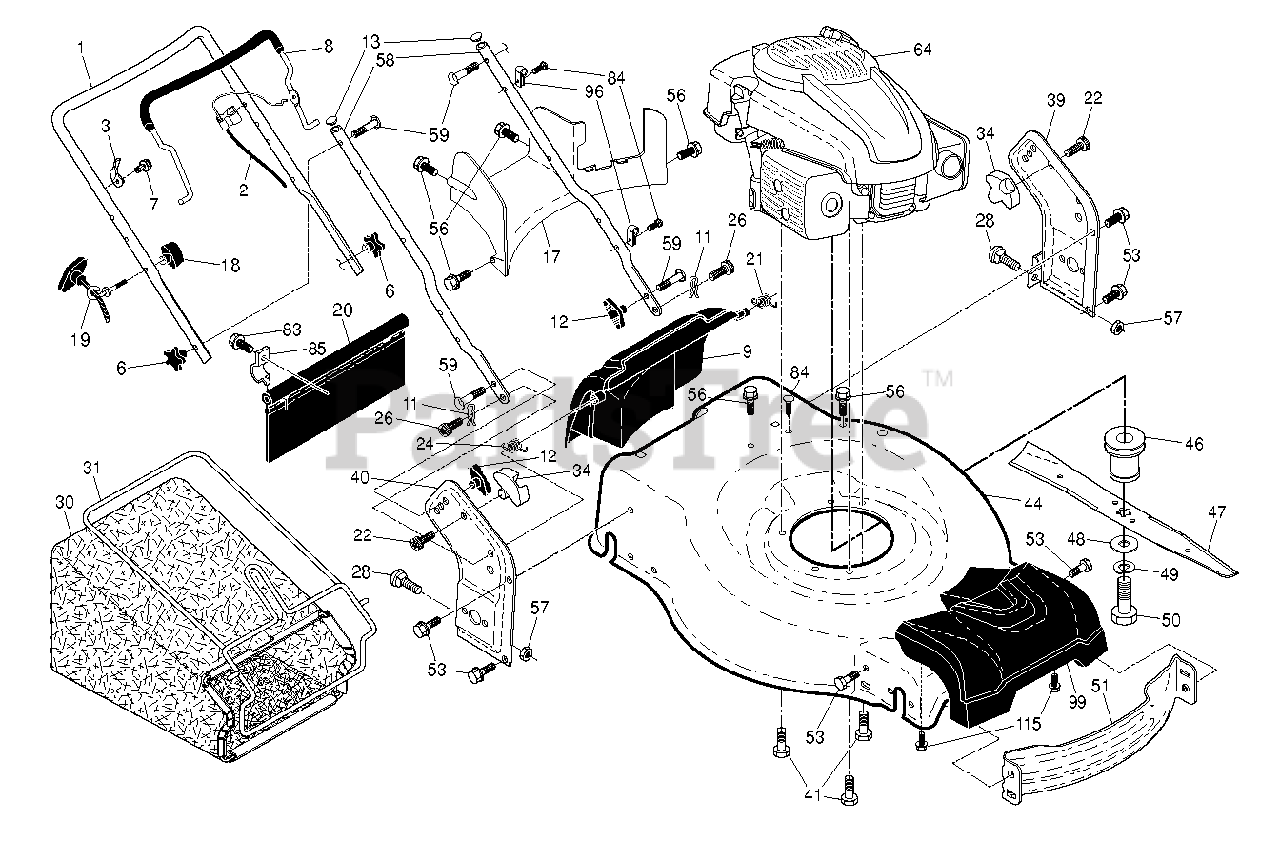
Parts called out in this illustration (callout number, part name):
1	HANDLE.UP.DSTR.FG/RGD.BLACK
2	Cable, MZR Rgd Plus Strt
3	BRACKET.UPSTOP.RT
6	KNOB.HANDLE.PLASTIC.STAR.BLACK
8	Bail, OM Strt.Mzr.Black.428
9	DOOR.REAR.22+GEN.RG.EBA.BLK
11	COTTER.HAIRPIN.DOOR/HANDLE.PIV
12	KNOB, DEFLECTOR
13	PLUG.PLASTIC.7/8".14-20.GAUGE
17	Rear Baffle, 22+ Rgd AWD Plastic
18	T-Knob, New Rope Guide
19	Rope Guide, Blk Zinc Chrom
20	SKIRT.REAR.22+RGD.
21	SPRING.LH.GRAY
22	SCREW.PAN.HEAD.#10
24	SPRING.RH.GRAY
26	SCREW,DOOR/HANDLE.PIVOT
28	Carriage Bolt, 5/16-18 X 5/8
30	GBAG.A3610010.BLK.GENERIC
31	Grass Bag Frame, 22+ Black
34	BRACKET.GRASSBAG.ATTACHING.BLK
39	Handle Bracket Assembly, LH 22+ Black
40	Handle Bracket Assembly, RH 22+ Black
41	BOLT 3/8-16X1-1/8
44	HOUSING.22+AWD.RR.HD.WO.REDTRI
46	Blade Adapter, 25mm
47	BLADE.22PLUS
48	WASHER,HARDEN
49	LOCKWASHER
50	SCREW, HEX HD 3/8-24 X 1-3/8
53	BOLT.5/16HEX.WHS.HD
56	SCREW.HX.13X.750
57	NUT.FLANGE.5/16
59	BOLT, HANDLE 5/16-18X1.75
83	TAPPING SCREW
84	FASTENER.PUSH.O.250X0.783
85	BRACKET.SKIRT.22+.BZP
96	CLIP.CABLE.BLK
99	COVER.ASM.FRONT JONSERED AWD
115	SCREW, HEX HD TAPPING #10-24 1
